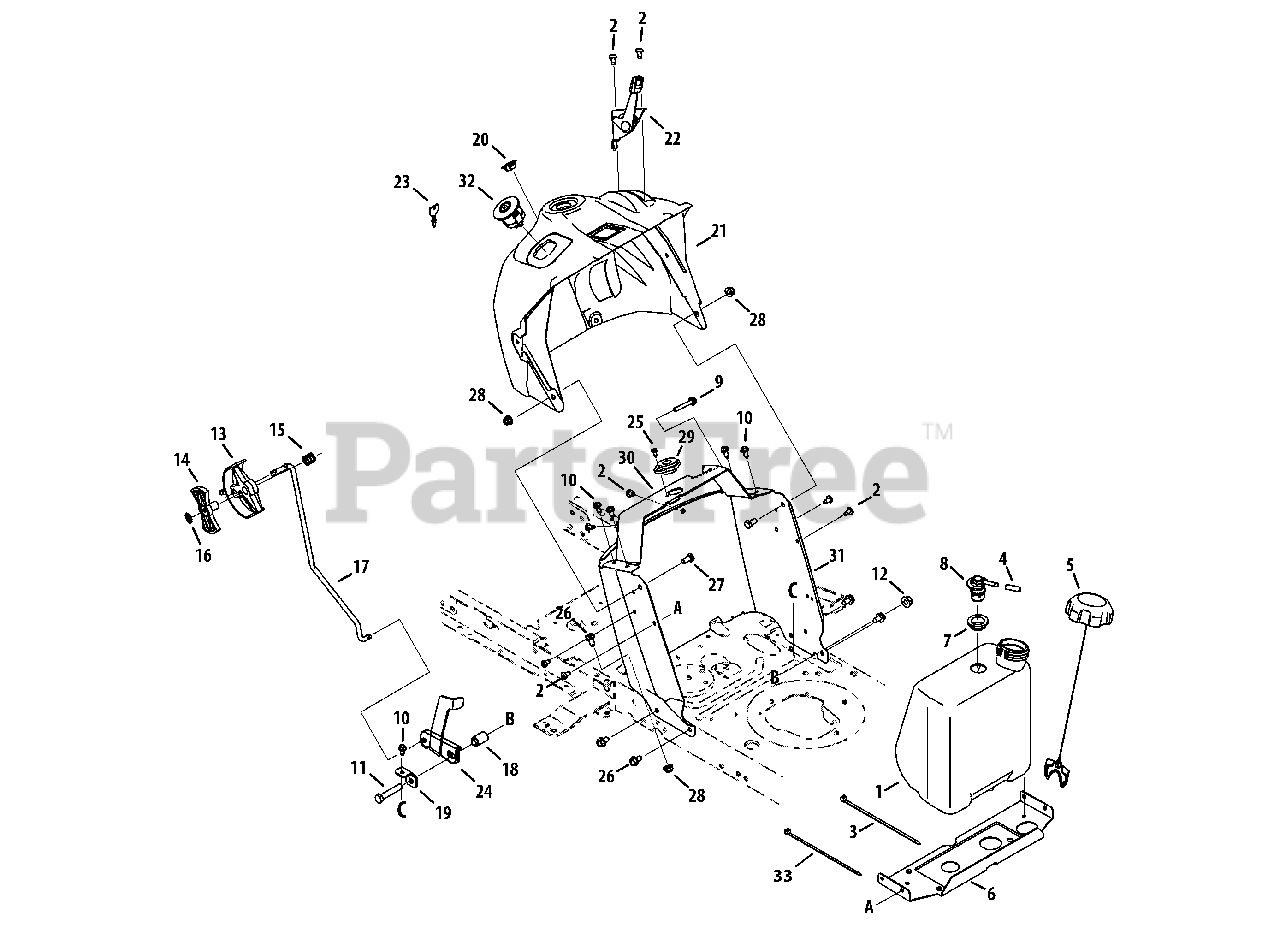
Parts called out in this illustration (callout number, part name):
1	Fuel Tank, 1.36 Gal.
2	Screw, Tap, 1/4-20, 0.500
3	Cable Tie, 36.0 Long
4	Hose Vent
5	Fuel Cap, 2.25"
6	Gas Tank Support Bracket
7	Rubber Grommet, 23 x 3.55
8	Rollover Valve
9	Hex Screw, 1/4-20 x 1.50
10	Tap Screw, 1/4-20, 0.625
11	Hex Screw, 3/8-16, 2.00, Gr5, Std
12	Flange Lock Nut, 3/8-16
13	Shift Lever
14	Index Control, 6 Speed
15	Compr. Spring, .685 OD x .63
16	Lock Washer, 1/4
17	Speed Selector Control Rod
18	Flng Spacer, .390 X .671 X 1.095
19	Speed Latch
20	Choke Plug
21	Dash, Upper
22	Throttle/Choke Cable Assembly
23	Key, Assembly
24	Speed Latch - No RMC
25	Screw, #10-16 x .500
26	Tap Screw,5/16-18, 0.625
27	Hex Screw, 5/16-18 x .625
28	Flange Lock Nut, 5/16-18
29	Bearing, .628 ID x 1.36
30	Bracket, Steering Support
31	Dash, Lower no window
32	Key Switch
33	Cable Tie
